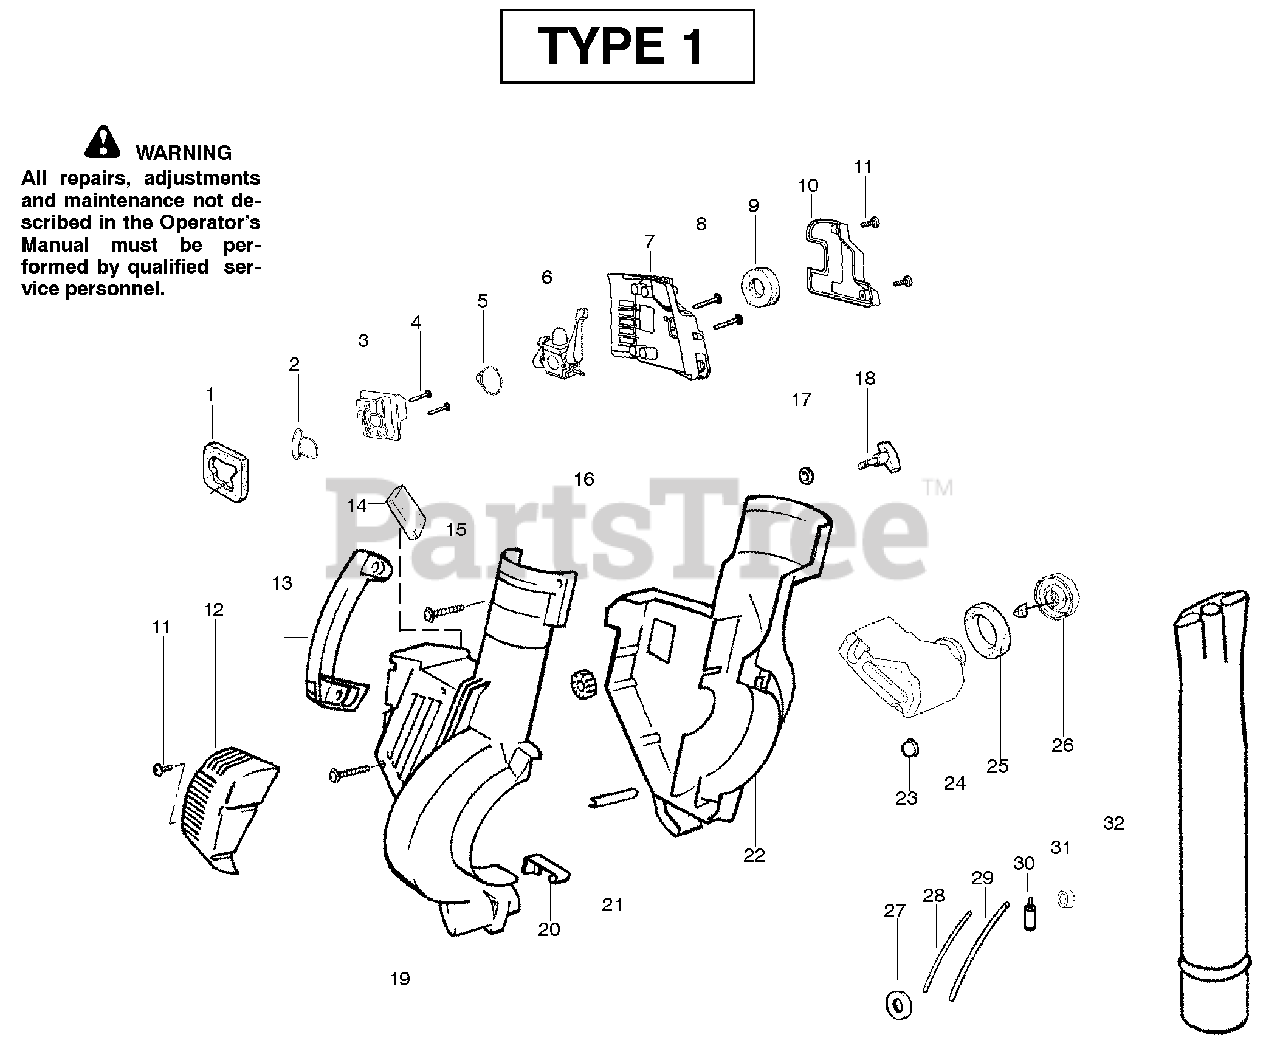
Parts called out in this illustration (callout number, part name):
1	Air Dam (kit)
2	Gasket-Adapter (kit)
3	Carburetor Adaptor
5	Gasket-Carburetor (kit)
6	Kit-Carb Ass'y. (C1Q-W11C)
6	Kit-Carb Ass'y. (WT-606)
8	Screw-Carb.
9	Filter-Air
10	Cover-Air Filter
12	Guard-Muffler
14	Foam 71.12mm (Kit)
16	Isolator
18	Knob-Blower
19	Housing-Right
20	Spring-Cover Latch
21	Guide-Starter Rope
22	Housing-Left
23	Isolator-Crankcase
24	Assy-Fuel Tank
25	Gasket-Fuel Tank
26	Fuel Cap w/Retainer
27	Grommet-Shroud
28	Kit-Line Carb/Purge
29	Kit-Line Tank/Purge
30	Assy-Fuel Pick-up
31	Grommet-Fuel line (kit)
32	Tube-Blower
